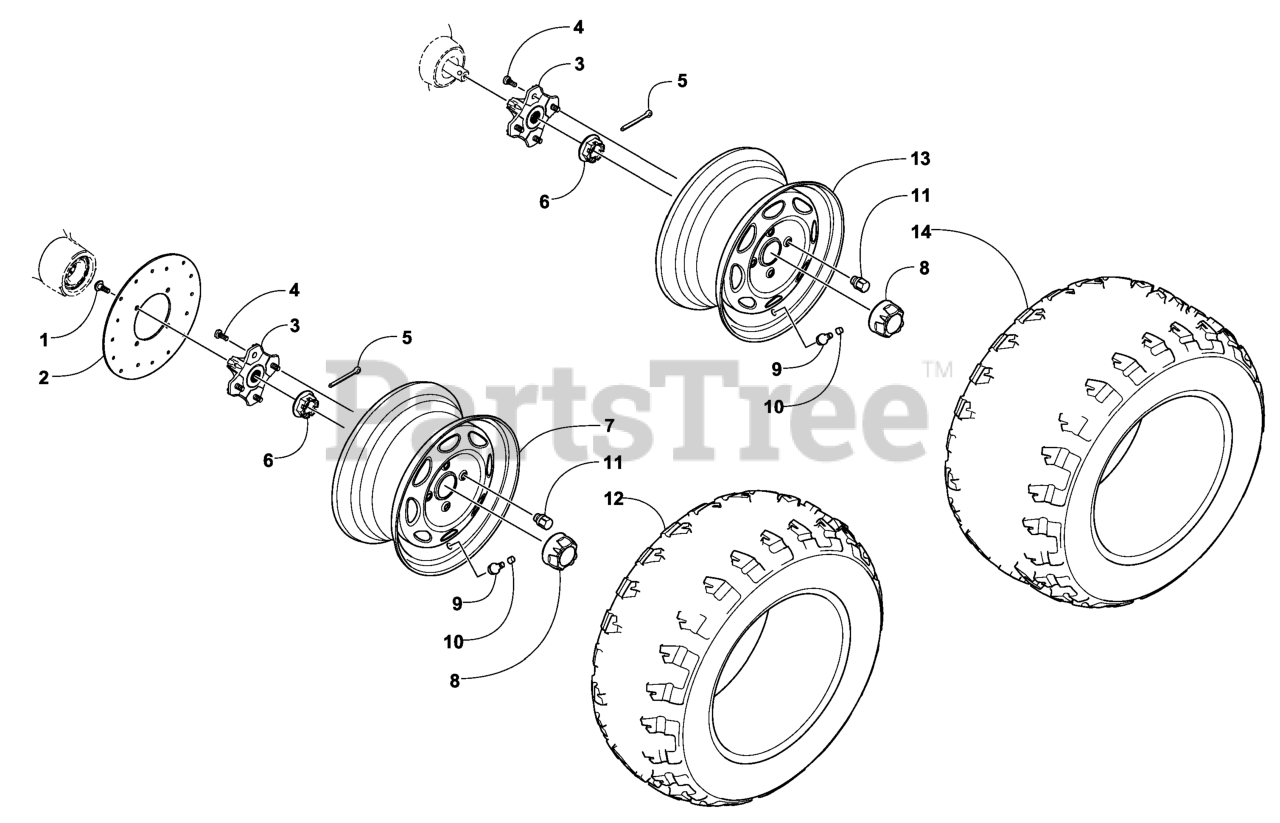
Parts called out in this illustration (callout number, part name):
1	SCREW-SHOULDER
2	KIT-BRAKE DISC
3	HUB ASM
4	STUD-WHEEL
5	PIN-COTTER
6	NUT-HHF, CASTLE
7	WHEEL-FRONT
8	CAP-WHEEL
9	VALVE STEM
10	CAP-VALVE STEM
11	NUT-LUG
12	TIRE (26 X 9 R14)
13	WHEEL-REAR
14	TIRE (26 X 11 R14)
